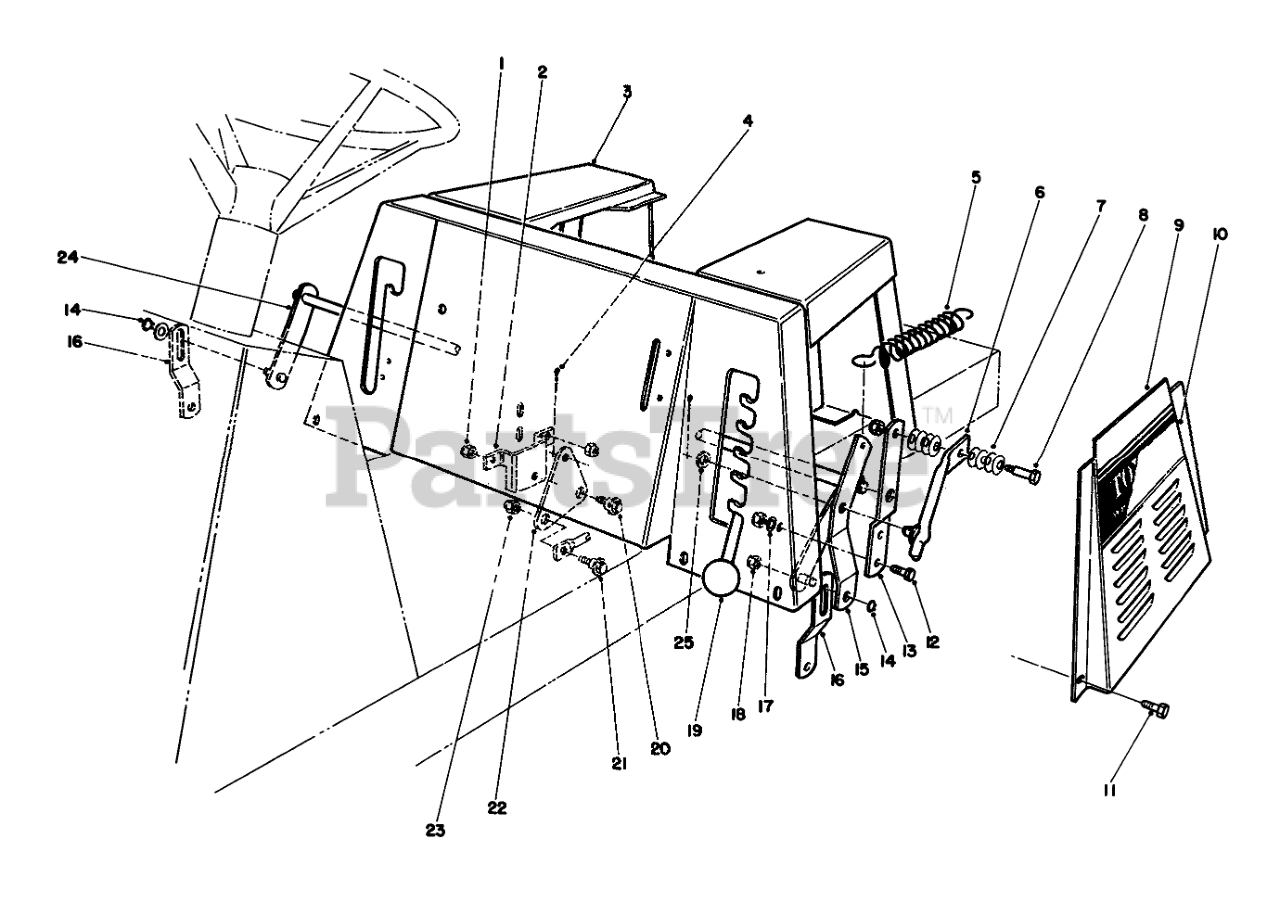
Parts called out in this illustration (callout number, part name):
1	NUT-LOCK, NI
2	BRKT-B.CRANK MTG
3	SEAT BODY WA R
4	PIN-COTTER
5	SPRING-EXTENSION
6	HOC LEVER WA B
7	WASHER-BELLEVILLE
8	BOLT-SHOULDER
9	L/H SEAT BASE PANELR
10	DECAL - LH TORO 12-32
11	SCREW-HH
12	SCREW-HH
13	Bracket
14	RING-RETAINING
15	Bracket-H.O.C., Engage
16	Link-Deck Suspension
17	WASHER-PLAIN
18	NUT-LOCK, NI
20	SCREW-SHOULDER
21	SCREW-SHOULDER
22	BELLCRANK
23	NUT-HEX
24	Arm
25	WASHER-FLAT
